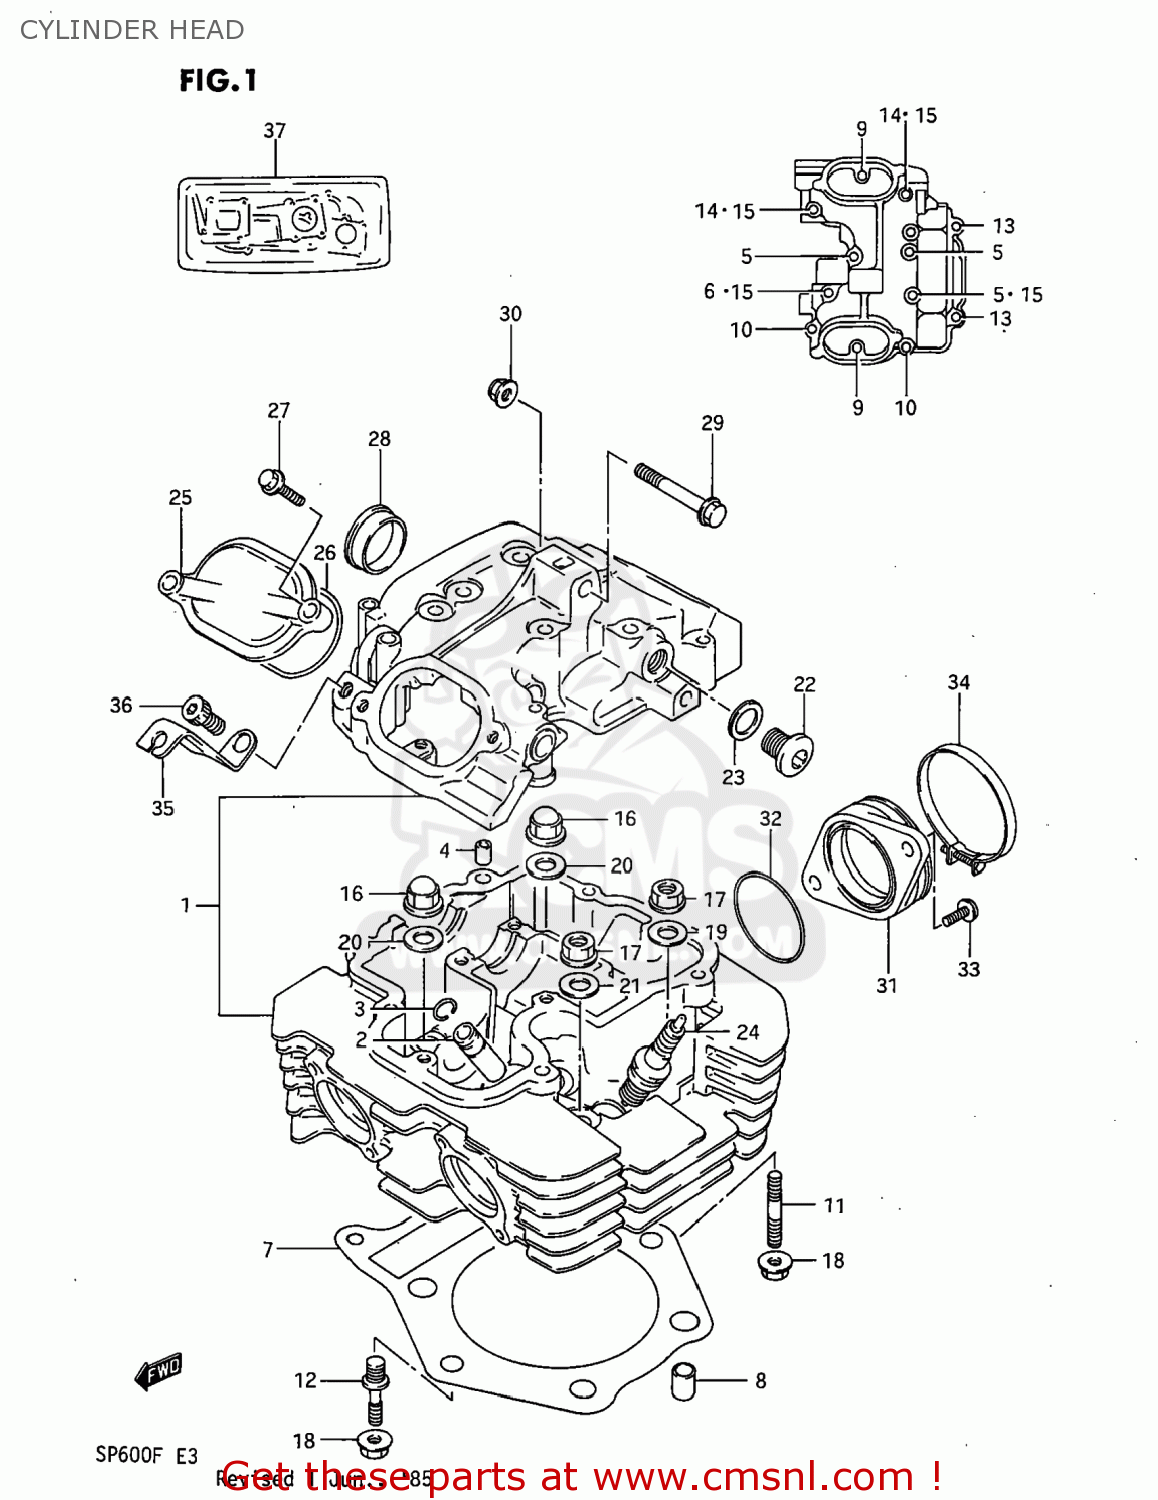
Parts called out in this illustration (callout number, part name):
1	HEAD ASSEMBLY,CYLINDER
2	GUIDE,VALVE
3	RING,SNAP
4	PIN(6.2X8X11)
5	BOLT (6X60)
6	BOLT 6X55
7	GASKET,CYLINDER HEAD (NAS)
8	PIN
9	BOLT
10	BOLT
11	STUD
12	STUD
13	BOLT(6X130)
14	BOLT (6X60)
15	WASHER
16	NUT
17	NUT
18	NUT 8MM
19	WASHER(10.5X22X2.3)
20	GASKET(10.5X22X2) (NAS)
21	WASHER(10.5X22X2.3)
22	PLUG
23	GASKET(14X19.2X2) (NAS)
24	SPARK PLUG DP9EA-9
25	CAP,INSPECTION
26	O RING(D:2.4,ID:23)
27	BOLT
28	PLUG(OD:30)
29	BOLT 8X50
30	NUT
31	PIPE,INTAKE
32	O RING(D:2.4,ID:45.7)
33	SCREW
34	CLAMP
35	LEVER,DECOMP SHAFT RH
36	BOLT
37	GASKET SET
